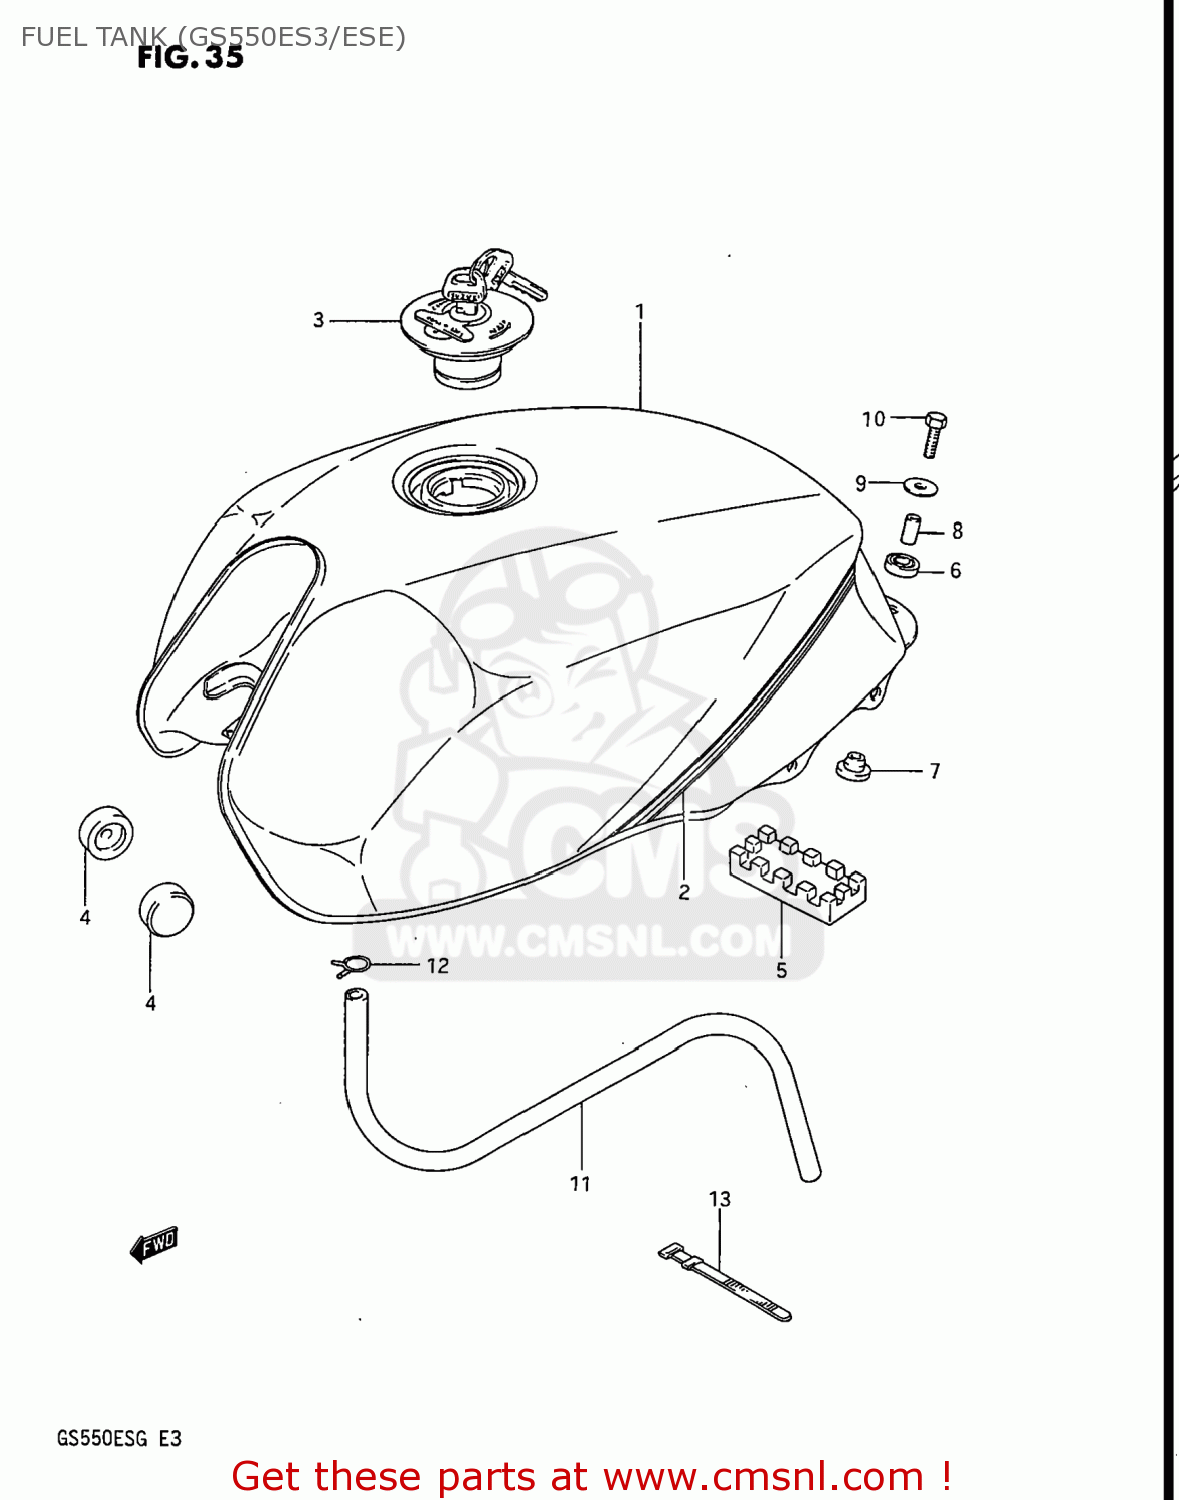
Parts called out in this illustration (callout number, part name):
1	TANK ASSEMBLY,FUEL
2	TAPE SET,FUEL TANK
3	CAP ASSY,FUEL TANK
4	CUSHION
5	CUSHION,FUEL TANK
6	CUSHION
7	CUSHION
8	SPACER (6.4X9X20)
9	WASHER (6.5X24X1.6)
10	BOLT
11	HOSE,FUEL
12	CLIP
13	CLAMP(L:187)
